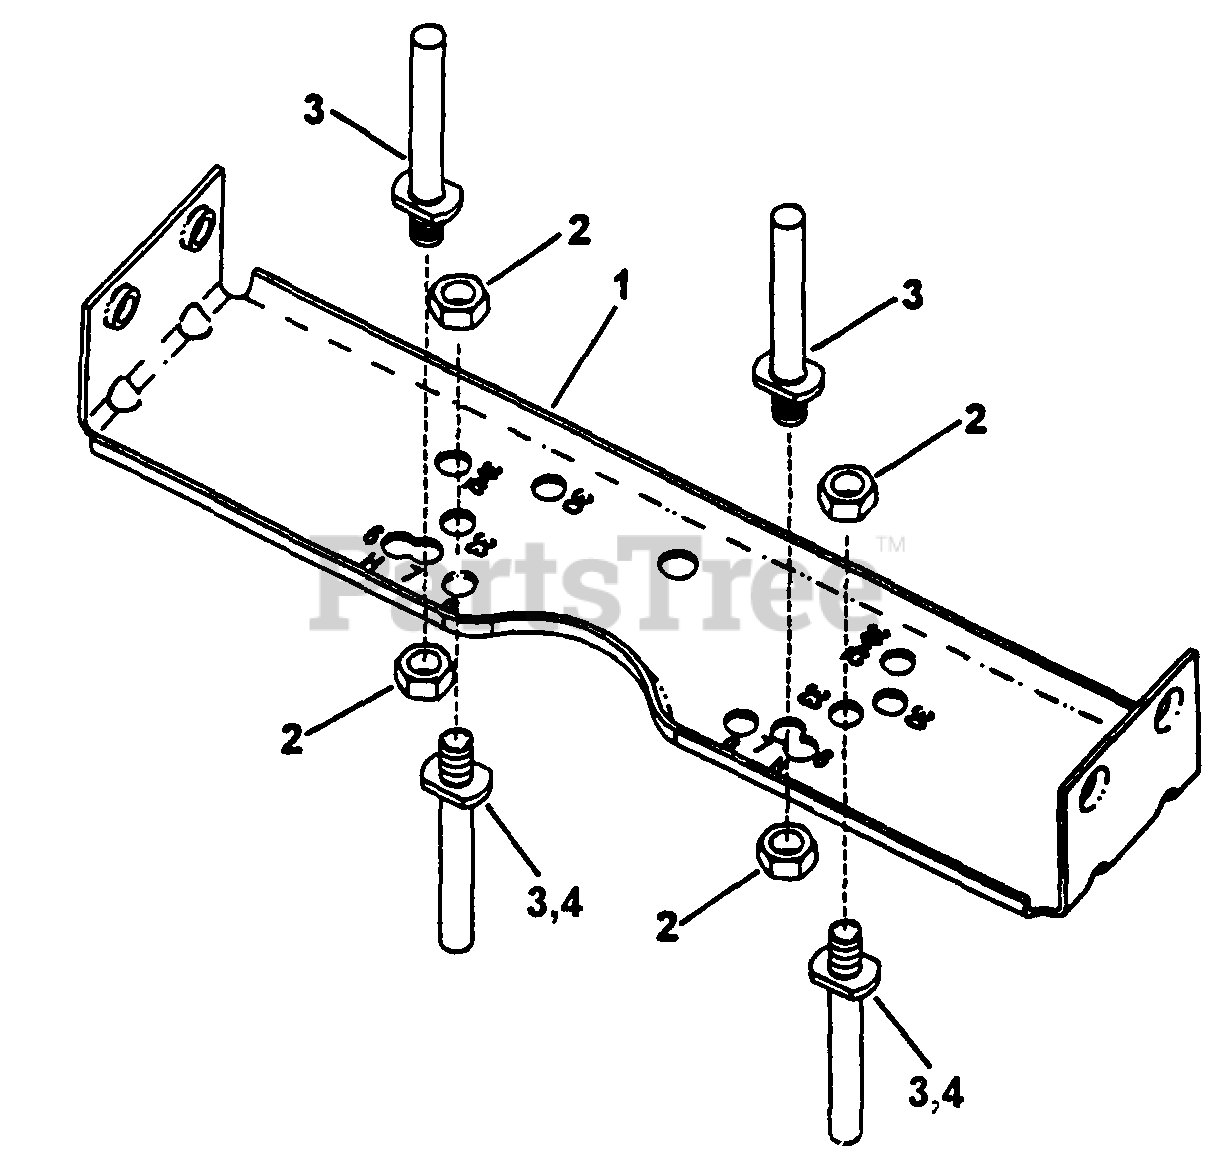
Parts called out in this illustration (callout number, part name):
1	BRACKET, Belt Guide
2	NUT, 5/16-18 Hex Center Lock, Gr. B or 5
3	STUD, Belt Guide, 2-7/8" L (2 or 4)
4	STUD, Belt Guide, 2-1/2" L (33" Hydro)
